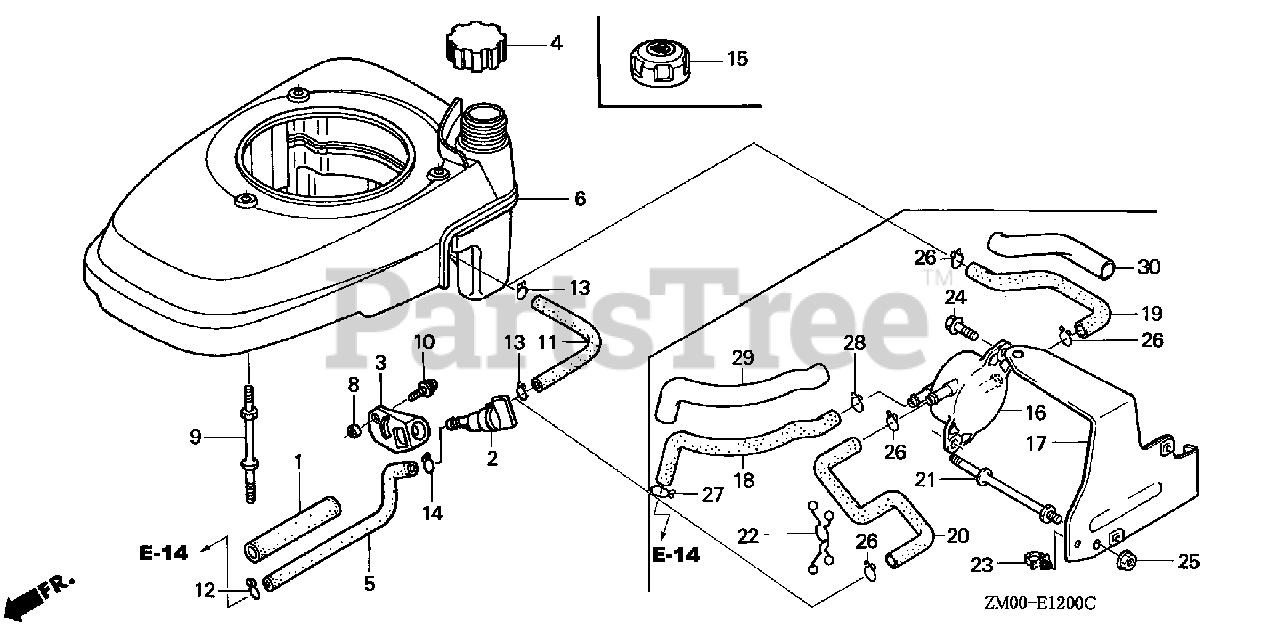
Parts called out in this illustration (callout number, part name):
1	RUBBER, SUPPORTER (107MM)
2	PETCOCK ASSY. (MAN)
3	BRACKET, PETCOCK
4	CAP ASSY., FUEL TANK
5	TUBE, FUEL
6	COVER, FAN *NH1* (BLACK)
8	COLLAR, FUEL COCK
9	BOLT, STUD
10	SCREW-WASHER (5X10)
11	TUBE, FUEL TANK
12	CLIP, TUBE (B8)
13	CLIP, TUBE (B10)
14	CLIP, TUBE (C9)
